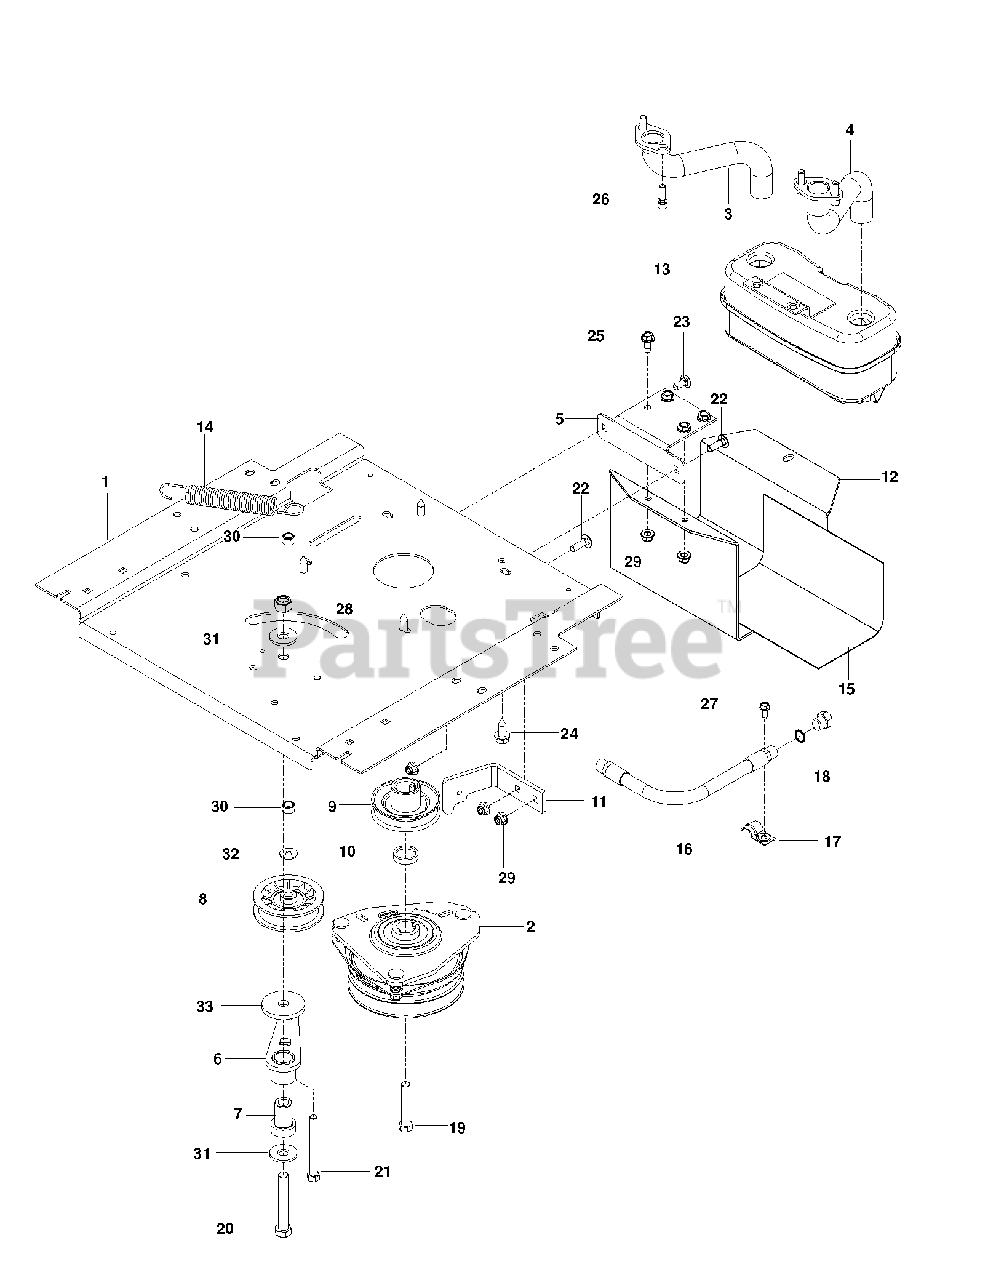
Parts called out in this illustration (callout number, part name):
1	PLATE, ENGINE BLK
2	CLUTCH.ELECTRIC.LT.48"*
3	PIPE.EXHAUST.RH.CV18/20
4	PIPE.EXHAUST.LH.CV18/20
5	BRACKET, MUFFLER, BLACK
6	IDLER ARM WELDMENT
7	IDLER SPINDLE
8	PULLEY, IDLER RAKE & ZTR
9	RP PULLEY, ENGINE
10	SPACER, HUB PULLEY
11	CLUTCH STOP OGR BLK
12	GUARD.MUFFLER.BLACK
13	MUFFLER ASM TWIN
14	SPRING, DECK DRIVE
15	HEAT SHIELD
16	HOSE.ASSEMBLY.OIL.DRAIN
18	PLUG OIL DRAIN
19	CLUTCH BOLT7/16-20X2.5 GR524HR
20	HCS 1/2-13 X 3-1/4 GD 5 ZD
21	HCS 3/8-16X3 1/2 GR5
23	BOLT 5/16-18 X3/4 ZN/YEL GR 5
24	RHSNB 5/16C X 1
25	SCREW
26	SCREW.SOCKET.HEAD.5/16-18
27	SCREW 1/4 X 5/8
28	RP NUT 1/2-13 HEX NYLOC ZD
29	5/16-18 NYLOC FLANGE NUT
30	NUT 3/8-16 NYLOC
31	WASH USS FLAT 1/2
32	WASHER 5/16 FLAT
33	HEAVY WASHER
